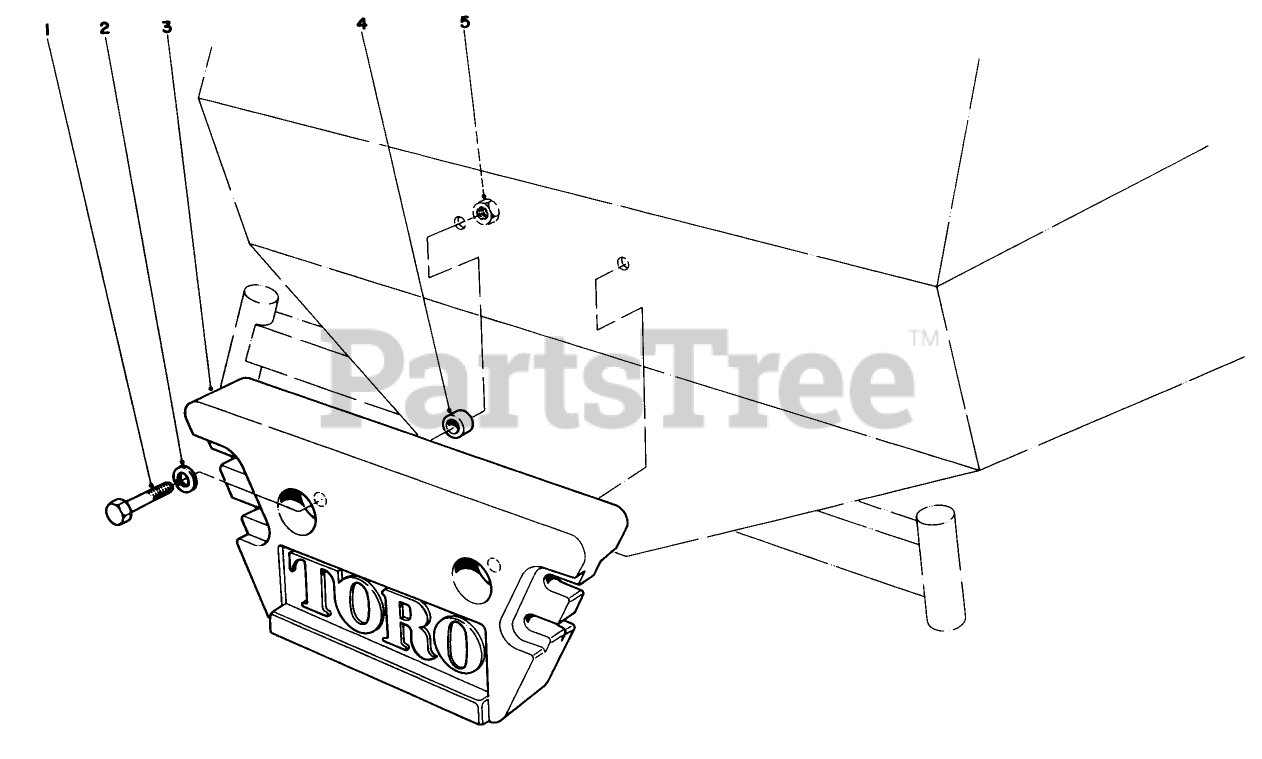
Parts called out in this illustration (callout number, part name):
1	SCREW-HH
2	SCREW-HH
4	SPRING ANCHOR BSHG
5	NUT-HH
